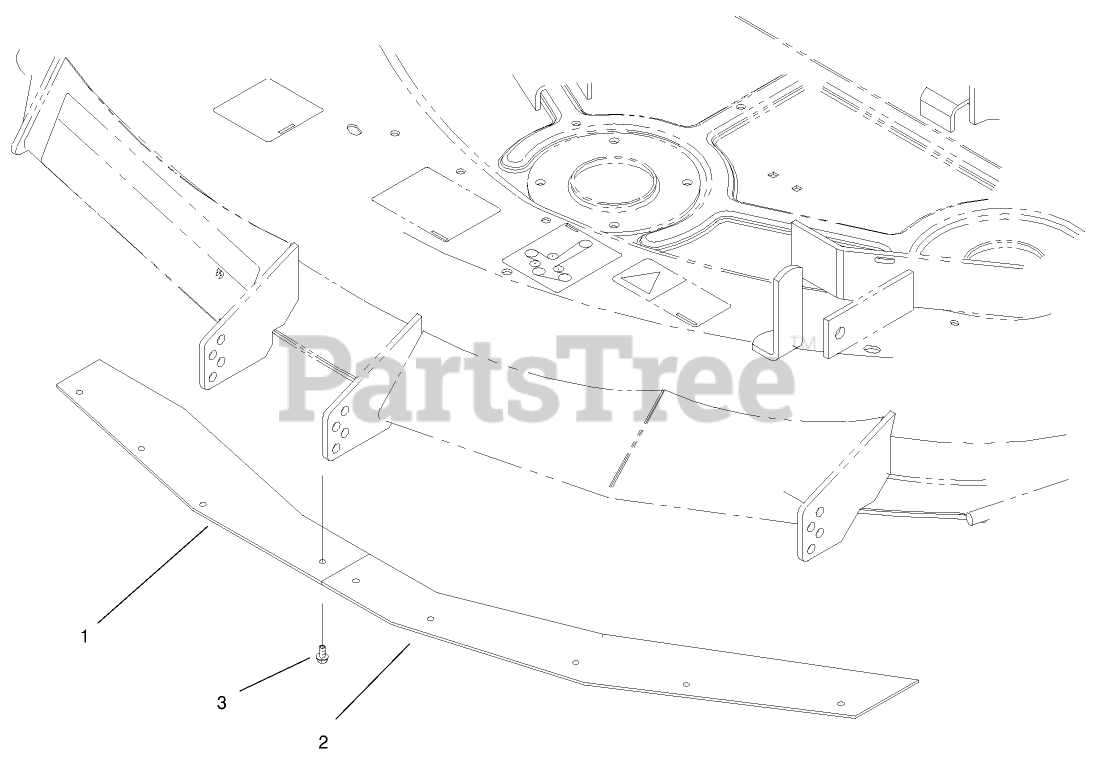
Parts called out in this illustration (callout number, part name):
1	PLATE-BLOWOUT, RH
2	PLATE-BLOWOUT, LH
3	SCREW
